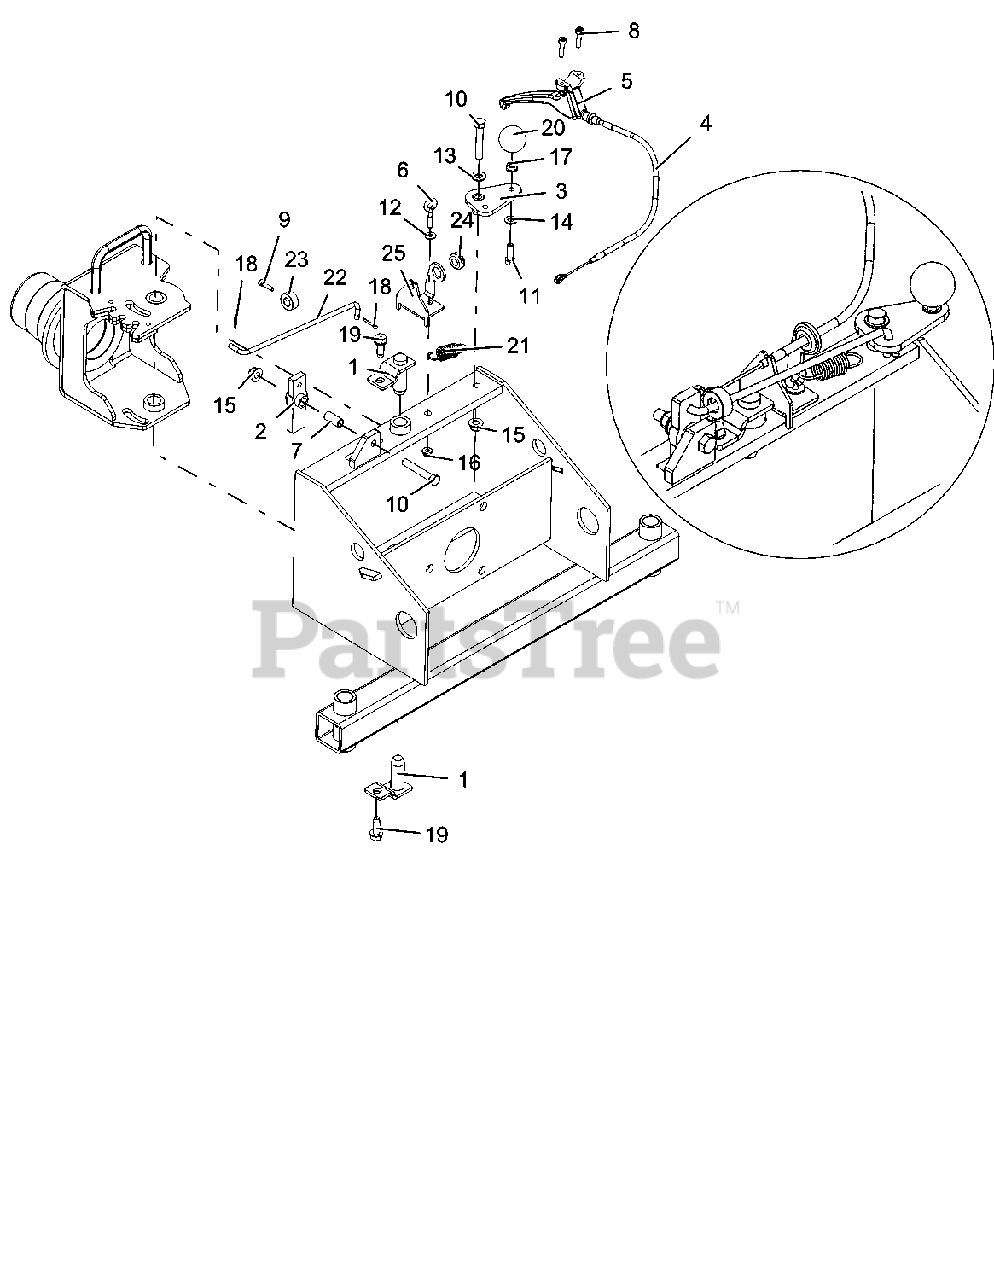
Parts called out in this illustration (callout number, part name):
1	WLDMT, BRUSH PIVOT PIN
2	WLDMT, PIVOT FRAME
3	WLDMT,BRKT
4	CABLE ASSY, BRUSH
5	HANDLE, ANGLE CONTROL
6	EYEBOLT, ROD HANGER ZC120
7	BSHG-SLV .385X.500X1.045
8	SCR,SKH M6-1.0X25 10.9CRKFCTR
9	SCR, SKH M5-.8X20 12.9ZC120
10	BLT,HEX .38-16X2.25 G5ZC120
11	BLT,HEX .31-18X1.00 G5ZC120
12	WSHR,FL-STL.281X.62X.065 ZC120
13	WSHR,FL-STL.406X.812X.065ZC120
14	WSHR,FL-STL.344X.688X.065ZC120
15	NUT,LK-NYL-FLG .38-16 G5ZC120
16	NUT,LK-NYL-FLG .25-20 G5ZC120
17	NUT,SPNLK-FLG .312-18 ZC120
18	PIN,CTR .12X.75EXTPRSQCT ZC120
19	SCR-TAP .38-16X1.00 HWH TR YZ
20	KNOB, BALL 5/16-18 X 1.5
21	SG-TENS .075X.75X2.25 WLD20.7
22	ROD,LINKAGE
23	COLLAR, LOCKING REVERSE
24	GROMMET, COVER MNT
25	CABLE BRKT
